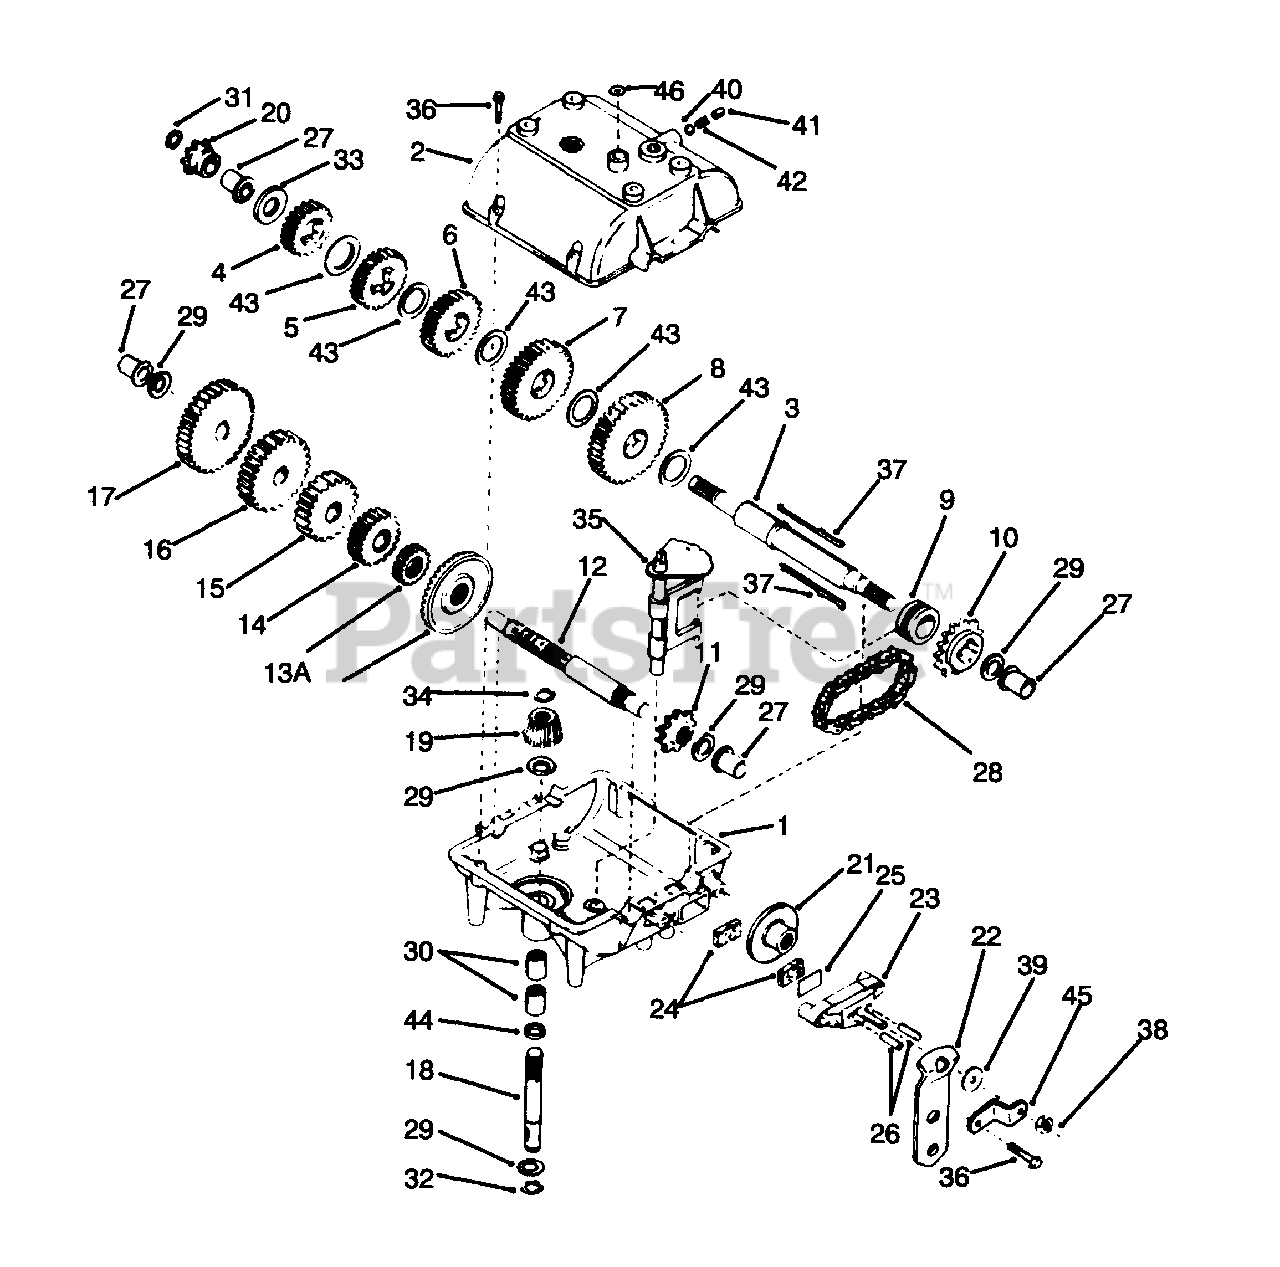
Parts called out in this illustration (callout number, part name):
1	Case-Transmission
2	Cover-Transmission
3	Shaft-Output
4	Gear-Spur (20 Teeth)
5	Gear-Spur (22 Teeth)
6	Gear-Spur (25 Teeth)
7	Gear-Spur (30 Teeth)
8	Gear-Spur (35 Teeth)
9	Collar-Shift
10	Sprocket (18 Teeth)
11	Sprocket (9 Teeth)
12	Shaft-Counter
13	Gear-Bevel (42 Teeth)
13A	Gear-Spur (15 Teeth)
14	Gear-Spur (20 Teeth)
15	Gear-Spur (25 Teeth)
16	Gear-Spur (28 Teeth)
17	Gear-Spur (30 Teeth)
18	Shaft-Input
19	Bevel-Pinion, Input
20	Sprocket (8 Teeth)
21	Disk-Brake
22	Lever-Brake
23	Holder-Pad, Brake
24	Pad-Brake
25	Plate-Pad, Brake
26	Pin-Dowel
27	Bushing-Flange
28	Chain-Roller (No. 41 Chain, 24 Links)
29	Washer-Thrust
30	Bearing-Needle
31	Ring-Retaining
32	Ring-Retaining
34	Ring-Retaining
35	Assy. Rod & Fork-Shift
36	Screw-Thread Forming
38	Nut-Lock
40	Ball-Steel
41	Screw-Set
43	Washer-Thrust
45	Bracket-Lever, Brake
46	Seal-Square Cut
